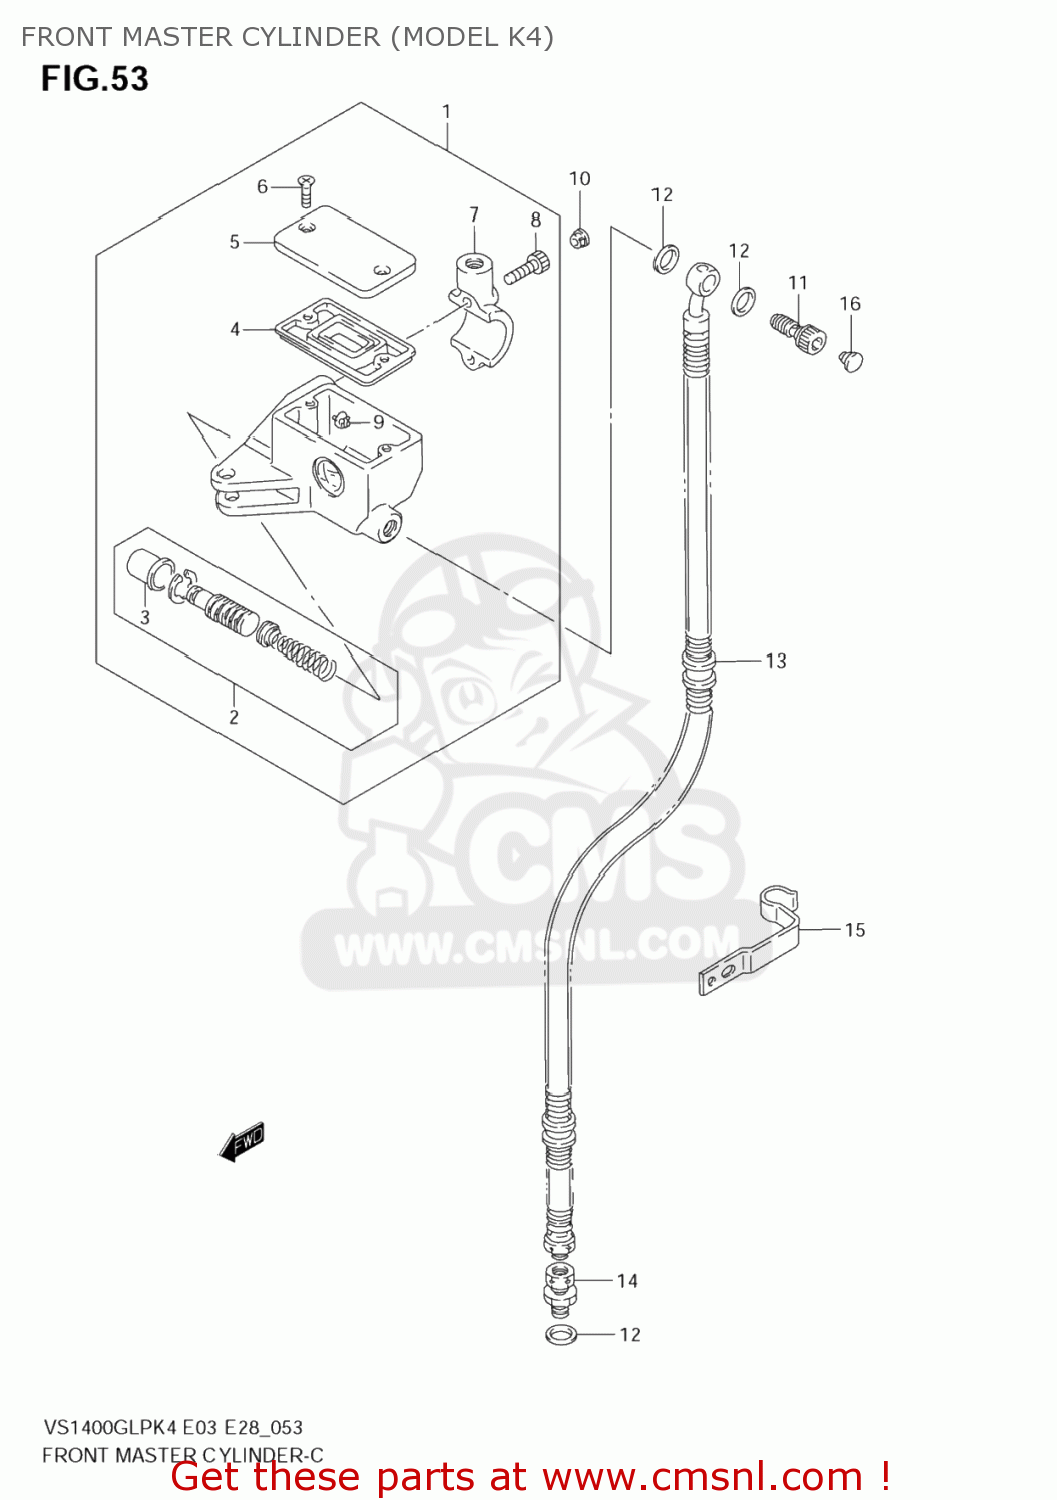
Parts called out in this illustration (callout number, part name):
1	CYLINDER ASSY,FR MASTER
2	PISTON/CUP SET
3	BOOT
4	5
5	CAP
6	SCREW
7	HOLDER
8	BOLT
9	PROTECTOR
10	CAP(OD:10)
11	BOLT UNION
12	WASHER(10X15X1.5)
13	HOSE,FR BRAKE
14	ADAPTER,BRAKE HOSE
15	GUIDE,BRAKE HOSE
16	CAP(OD:12)
